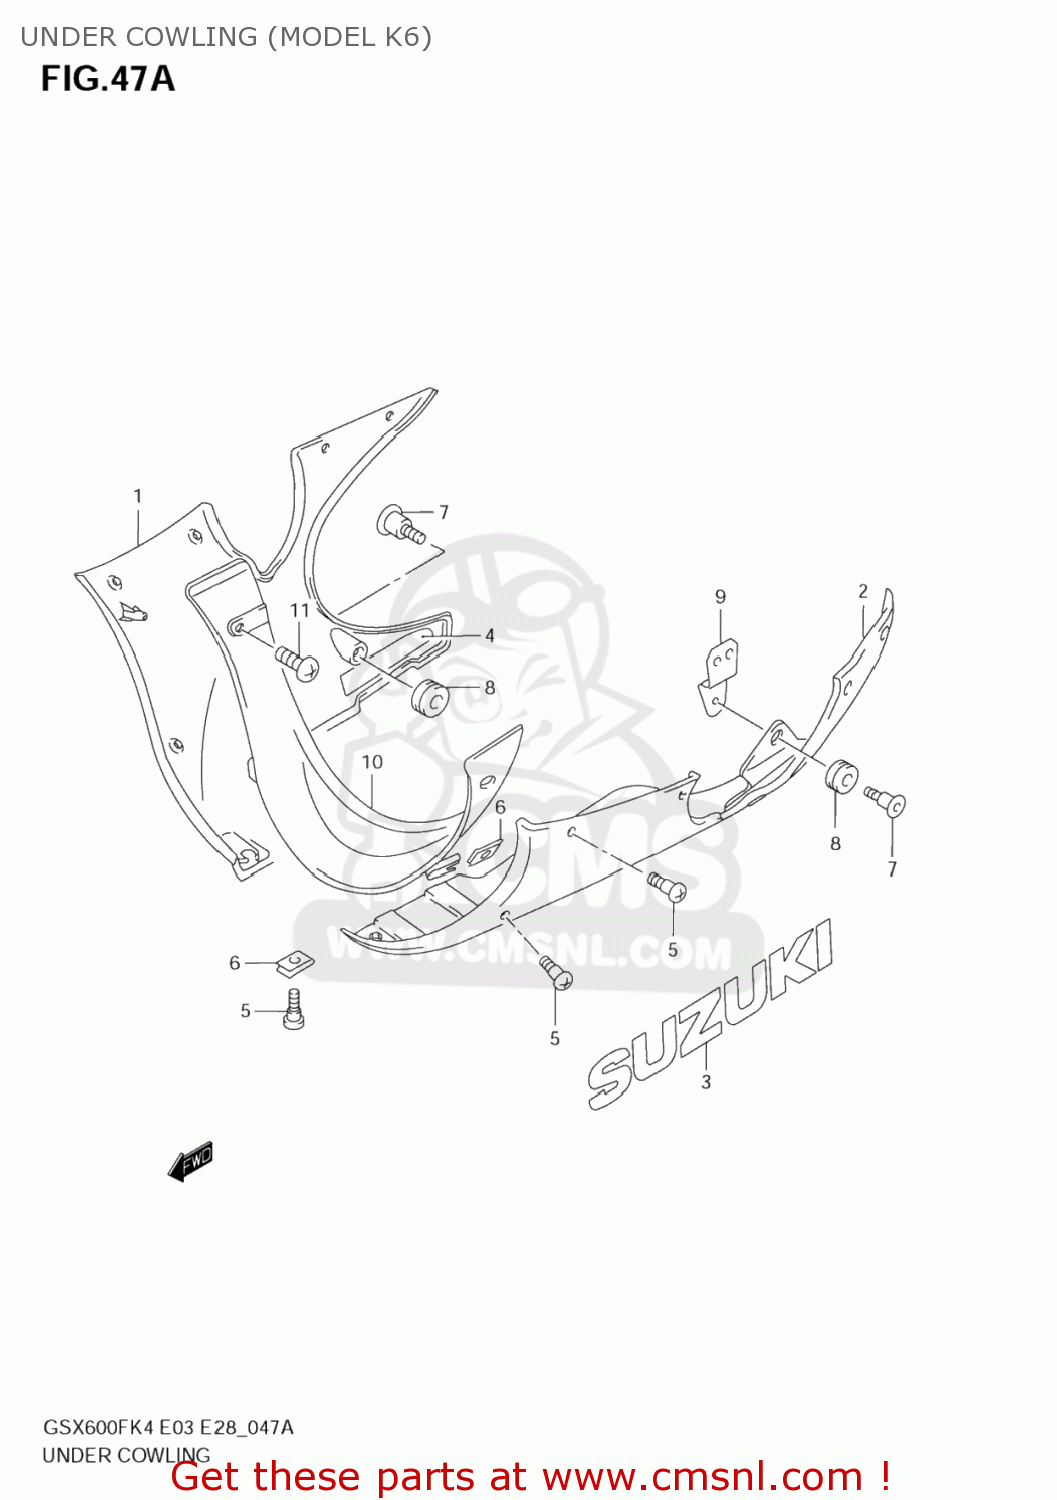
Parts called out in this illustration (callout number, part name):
1	COWLING ASSY,UNDER,R
2	COWLING,UNDER,L(BLACK)
3	EMBLEM,SUZUKI
4	SHIELD,COWLING UNDER,R NO.1
5	SCREW(5X16)
6	NUT,COWL
7	SCREW(6X20)
8	CUSHION
9	BRACKET,UNDER COWL,L & FRAME
10	COWLING,UNDER CTR
11	SCREW
